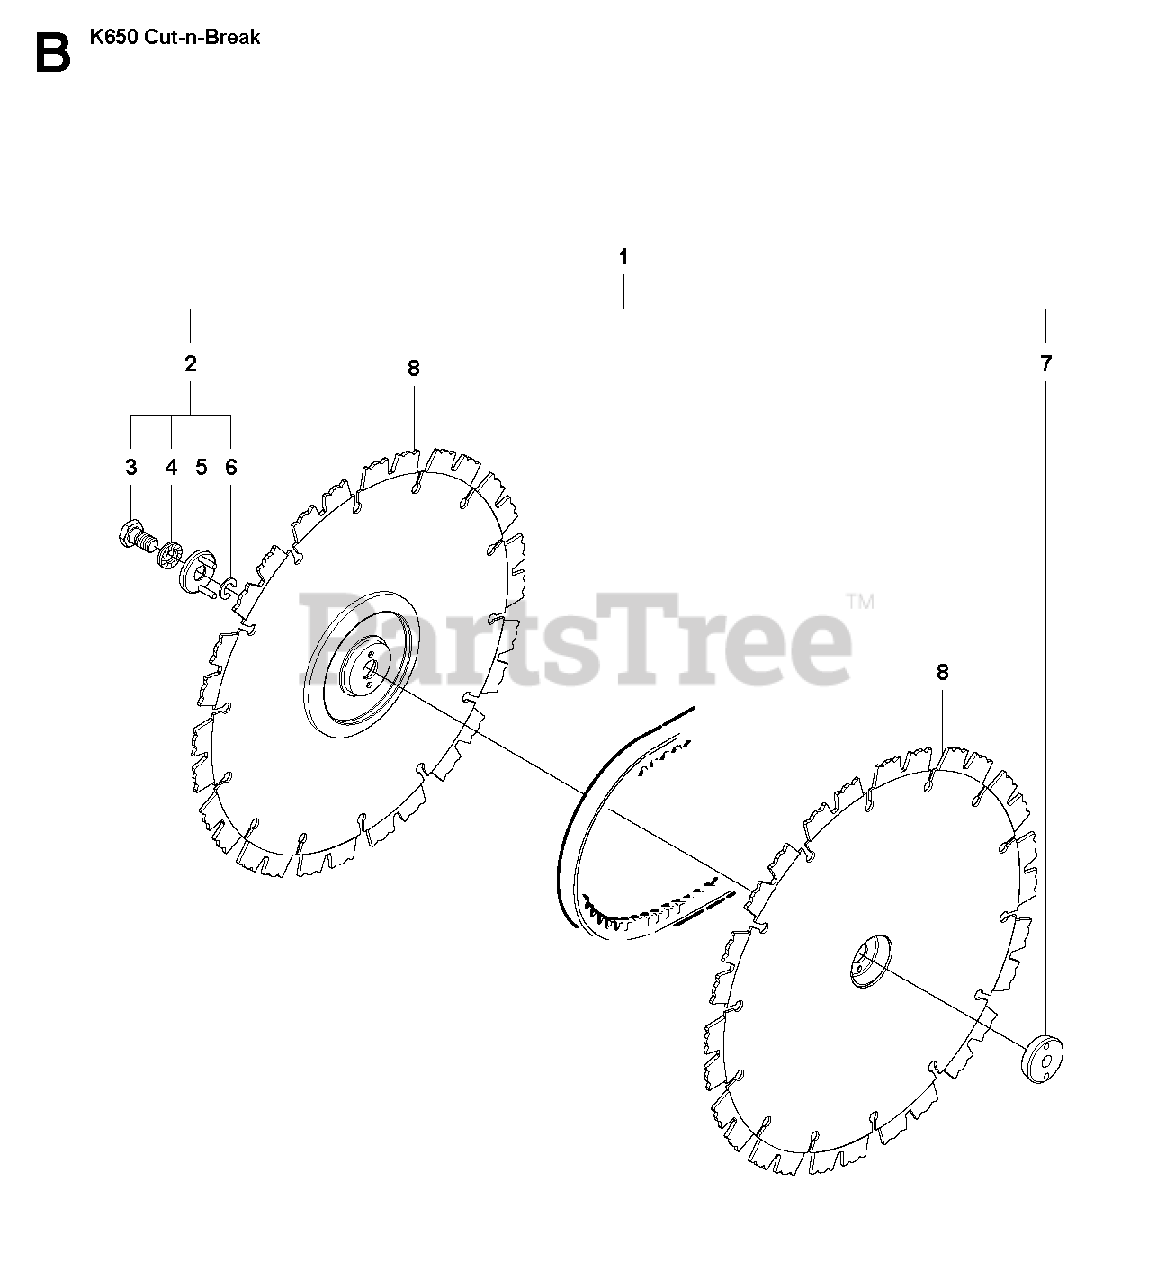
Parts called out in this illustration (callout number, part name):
1	SCREW KITIncl. 2, 7
6	RETAINER RING
8	DIAMOND BLADEEL20CB Soft
8	DIAMOND BLADEEL45CB Medium
8	DIAMOND BLADEEL70CB Hard
